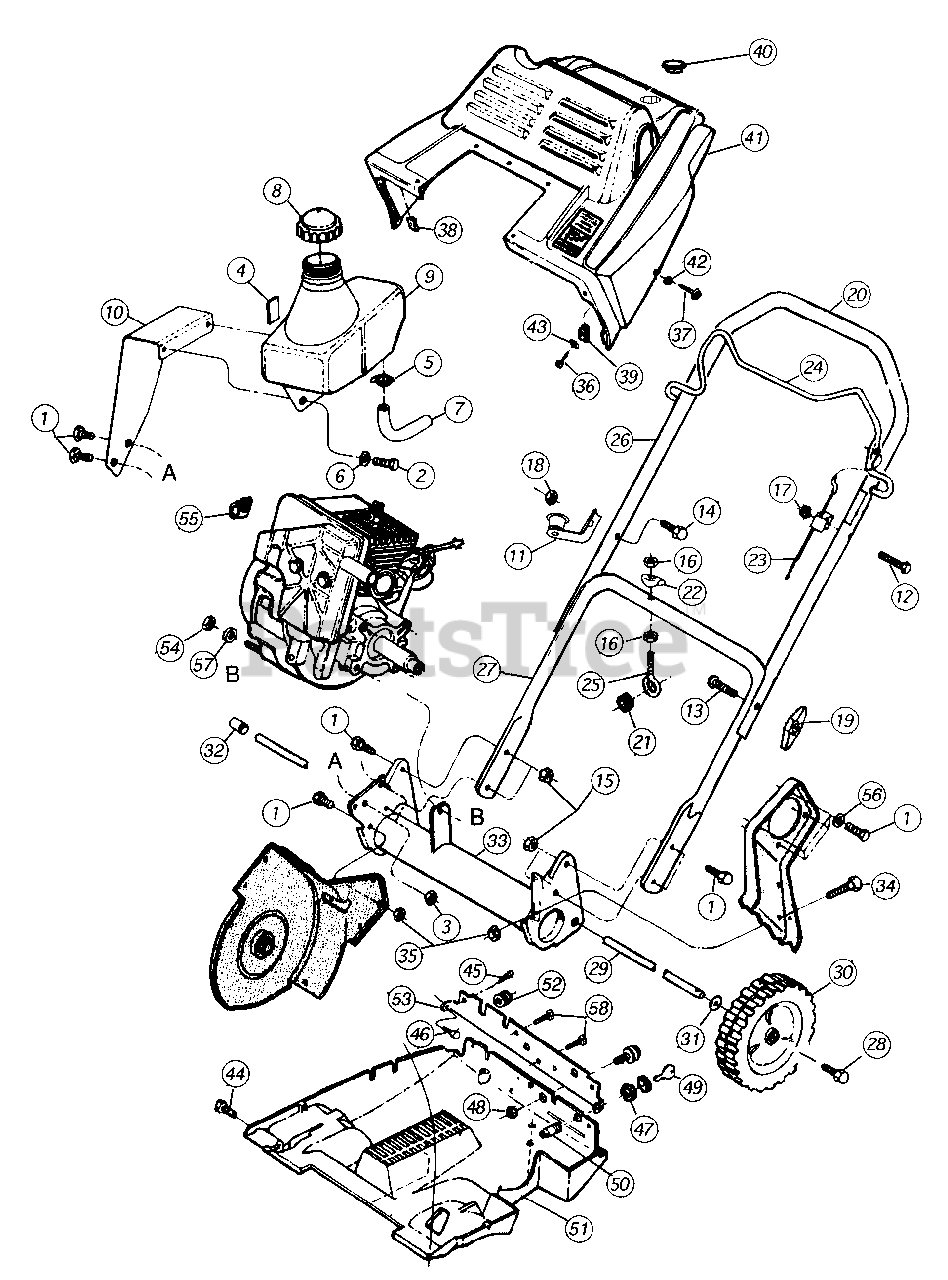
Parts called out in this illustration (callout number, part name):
1	Hex Screw: 5/16 - 18 x .75 Gr 2
2	Hex Screw: 1/4 - 14 x .625
3	Sems Nut
4	Foam Strip
5	Hose Clamp 1/2" OD
6	Flat Washer
7	Hose, Fuel Line
8	Fuel Tank Cap
9	Fuel Tank
10	Support Bracket
11	Bracket Assembly, Rope Guide
12	Hex Screw: 1/4 - 20 x 2.0 Gr 5
13	Carriage Bolt: 5/16 - 18 x 2.0 Lg. Carved
14	Oval C-Sunk Screw
15	Sems Nut
16	Hex Nut: 5/16 - 18
17	Sems Nut 1/4 - 20
18	Top Lock Nut 1/4 - 20
19	Knob Assembly
20	Foam Grip, Handle
21	Grommet: .44 ID x .94 OD x .50
22	Side Lock Washer
23	Drive Cable, Auger
24	Auger Bail, Drive Dipped
25	Eye Bolt 5/16 - 18
29	Axle, Tube
30	Wheel Assembly (Gray)
31	Flat washer: .510 ID x .75 OD x .03
32	Spacer
35	Sems Nut
36	Hex Screw
37	Ab Screw
38	Retainer Clip, U-Style
39	U Nut
40	Snap-In Plug
41	Upper Engine Cover (Gray)
42	Flat Washer
43	Flat Washer
44	Hex Screw: 1/4 - 20 x .625
45	Tap Screw: 10 - 24 x .75
46	Tap Screw: 10 - 25 x .75
47	Jam Nut: 5/8 - 32 x .12
48	Sems Nut 1/4 - 20
49	Ignition Key
50	Key Switch
51	Lower Engine Cover (Gray)
52	Grommet: .280 x .750 x .40
53	Control Panel
54	Sems Nut 5/16 - 18
55	Mounting Clamp
56	Lock Washer
57	Flat Washer
58	Tap Screw
